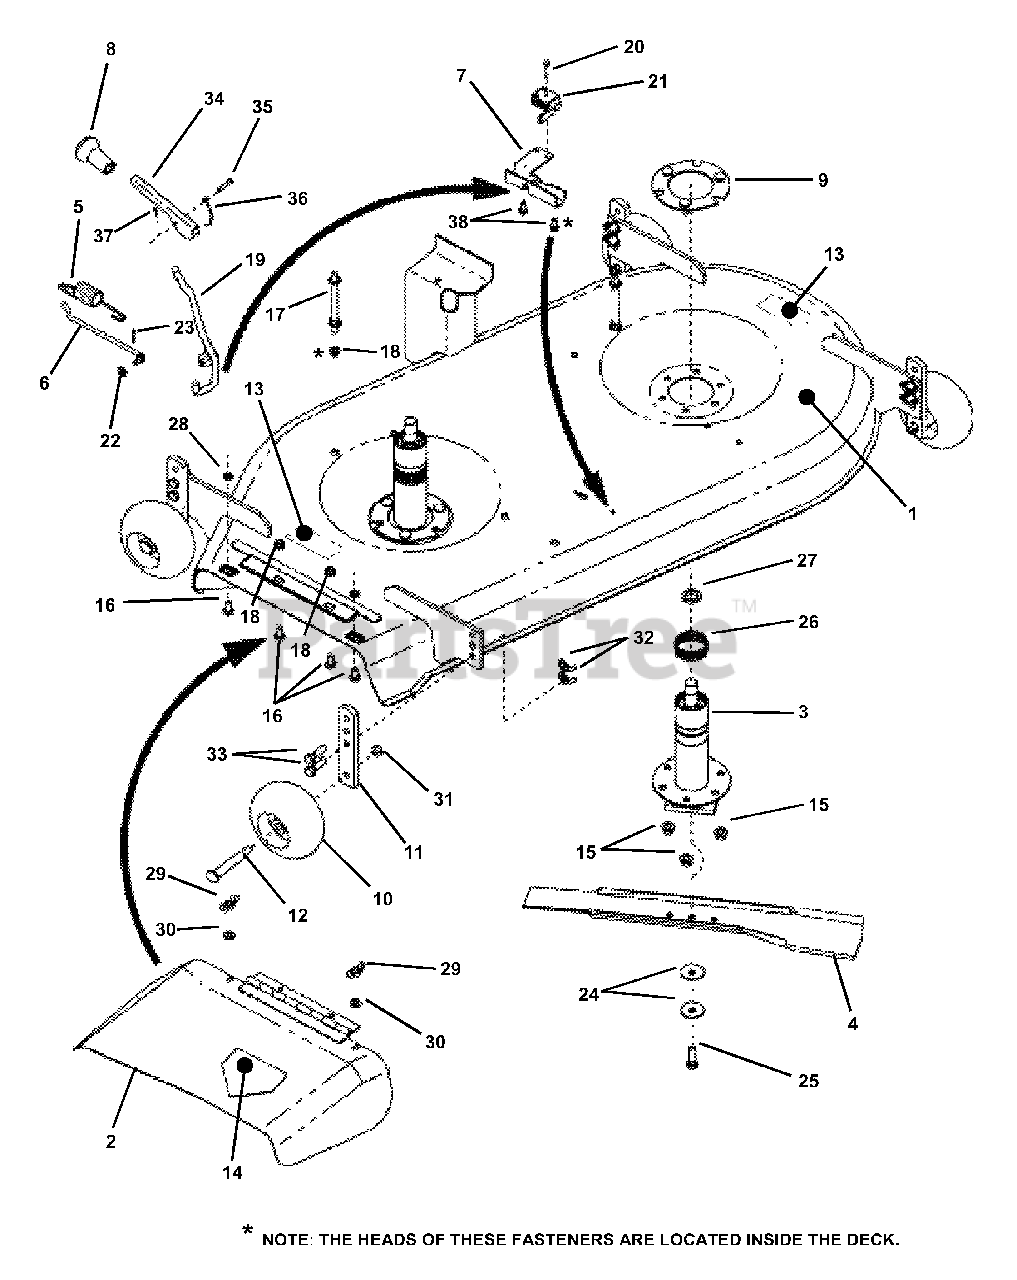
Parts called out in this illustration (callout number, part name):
1	WELDMENT, 42" Deck
2	ASSEMBLY, Side Chute
3	ASSEMBLY, Spindle
4	BLADE, 21" Standard Lift
5	SPRING, Belt
6	ROD, Idler
7	MOUNT, Handle
8	GRIP, Handle
9	ASSEMBLY, Spindle Ring
10	WHEEL, Gage
11	POST, Anti-Scalp
12	BOLT, Gage Wheel, 3/8-16 x 3-3/8" Hex Head Shoulder
13	DECAL, Caution
14	DECAL, Danger
15	NUT, 3/8-16 Hex Flange Lock
16	BOLT, 5/16-18 x 3/4" Short Neck Carriage, Grade 5
17	STAND-OFF, 3-1/2" long, 5/16-18 top, 3/8-16 bottom threads
18	NUT, 3/8-16 Hex Flange Lock
19	WELDMENT, Blade Engage Lever
20	SCREW, #10-32 x 1" Hex Washer Self-Tap, Grade 2
21	SWITCH, Deck Interlock (NO)
22	WASHER, 1/4" Flat
23	PIN, 3/32 x 3/4" Cotter
24	WASHER, Cone
25	SCREW, 3/8-24 x 1" Hex Head Cap, Grade 5
26	RING, Tolerance
28	RETAINER, 5/16" Bolt
29	WING-NUT, 5/16-18 Lock
30	WASHER, 5/16" Flat
31	NUT, 3/8-16 Hex Center Lock
32	WING-NUT, 3/8-16 Nyloc
33	SCREW, 3/8-16 x 1-1/4" Hex Head Cap, Grade 5
34	HANDLE, Blade Engagement
35	PIN, 3/16 x 1" Clevis
36	SPRING, Torsion
37	PIN, 3/32 x 1/2" Cotter
38	SCREW, 1/4-20 x 5/8" Hex Washer Self-Tap
